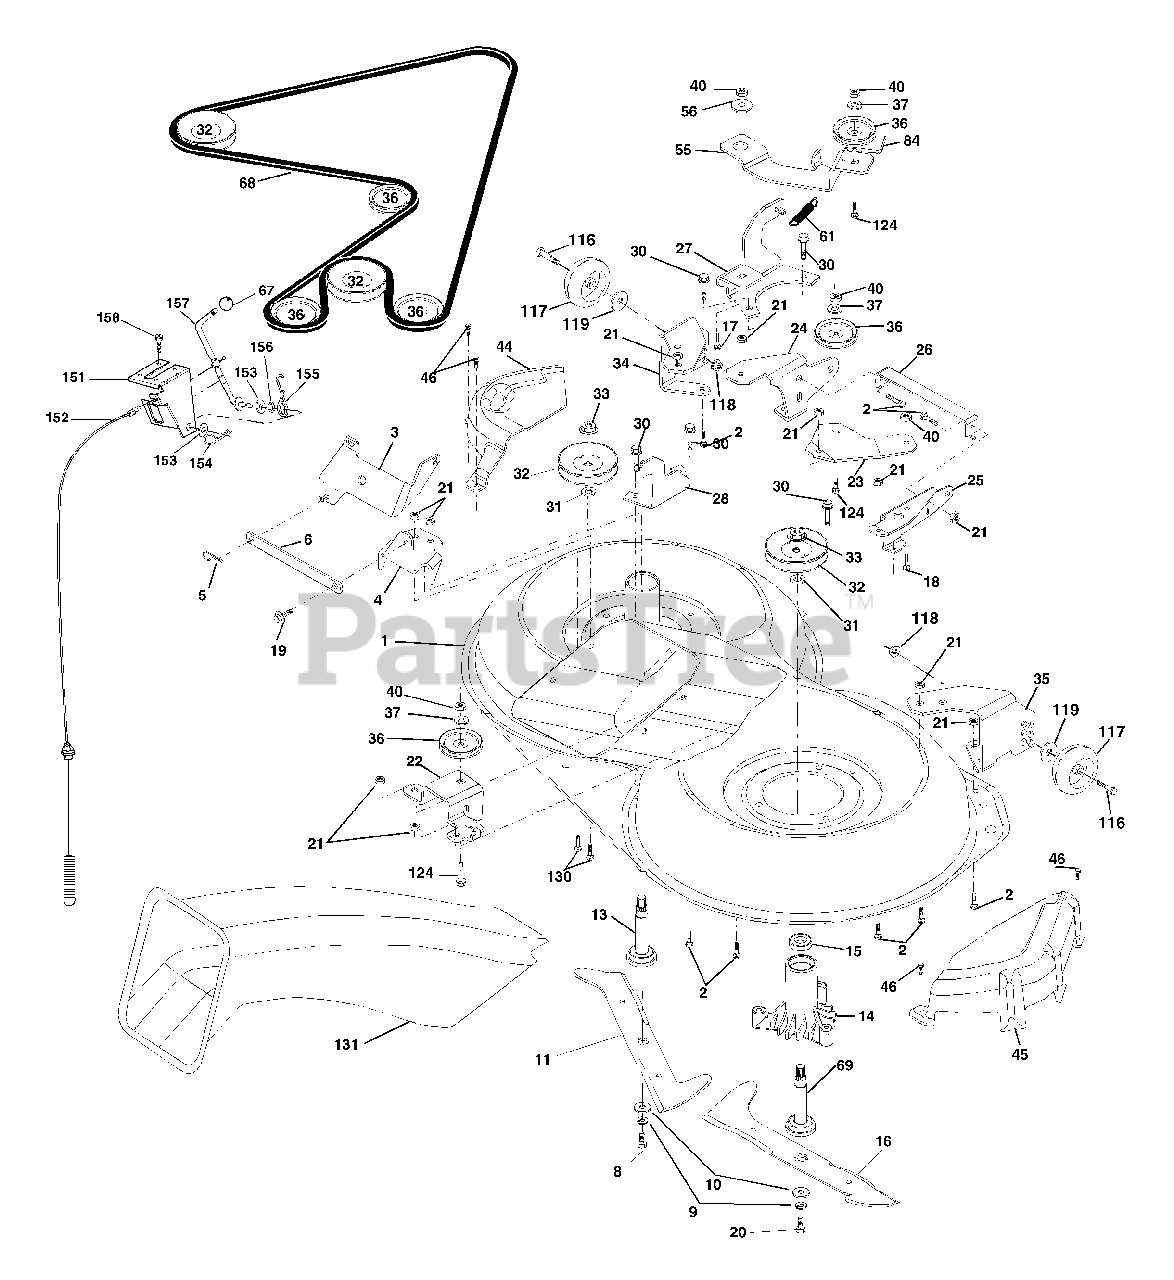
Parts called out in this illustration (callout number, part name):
1	Housing Asm. Mower 92 CRD
2	Bolt Rdhd Sqnk 5/16-18 Unc x 3/4
3	Bracket Asm. S-Bar Chass 92 CRD
4	Bracket Bar Sway Deck 92 CRD
5	Retainer Spring
6	Bar Sway 92 CRD
8	Bolt 3/8-24 x 1.25 Gr8 Patched
9	Washer Lock Hvy 3/8 Unplated
10	Washer Hard Blade Mower vented
11	Blade 3-1 Lh 92 CRD
12	Bearing Ball #6204 (Mandrel)
13	Shaft Asm. W/Lower Bearing
14	Housing Mandrel Vented (Machd)
15	Bearing Ball Mandrel
16	Blade 3-1 Rh 92 CRD
17	Bolt Carriage 3/8-16 x 1-1/4
18	Bolt Rdhd Sqnk 3/8-16 x 1 Gr5
19	Bolt Shoulder 5/16-18 Thd Form
20	Bolt 3/8-24 x 1.25 Gr8 Ptch Lhthd
21	Nut Crown Lock 5/16-18
22	Bracket Idler Sprt RR 92 CRD
23	Bracket Idler Sprt RF 92 CRD
24	Bracket Suspension LF 92 CRD
25	Bracket Suspension RF 92 CRD
26	Brace Support Susp Frt CRD
27	Bracket Asm. Susp RR 92 CRD
28	Bracket Asm. Susp LR 92 CRD
30	Screw Thd Rolling Washer Head
31	Washer Spacer Mower Vented
32	Mandrel Pulleys 36 & 46
33	Nut Flg Top Lock Cntr B 9/16
34	Bracket Gauge Wheel Lf 92 CRD
35	Bracket Gauge Wheel Rf 92 CRD
36	Pulley Idler V-Groove Dim 4.25
37	Washer 11/32 x 13/16 x 16 Ga
40	Nut Crownlock 3/8-16 Unc
44	Cover Mandrel Lh 92 CRD
45	Cover Mandrel Rh 92 CRD
46	Screw Thd Roll 1/4-20 x 5/8
55	Arm Idler 92 CRD
56	Spacer Retainer Mower
61	Spring Tension Belt
67	Knob Rd 3/8-16 Plstc Thds Blk
68	Hex-Belt 92 Mower 105AA
69	Shaft Asm W/Lwr Brg Rh Thd CRD
84	Keeper Belt Idler
116	Bolt Shoulder
117	Wheel Gage Donut Wide
118	Nut Centerlock 3/8-16 Unc
119	Washer 3/8 x 7/8 x 14 Ga.
124	Bolt Carr Sh 3/8-16 x 1-1/2 Gr5
128	Washer Felt
130	Bolt Rdhdsqnk 5/16-18 Unc x 3/4
131	Chute Bagger CRD 92cm
151	Bracket Clutch Cable
152	Cable Clutch CRD
153	Washer Flat 3/8" Type B
154	Spring Retainer
155	Spring Retention
156	Spacer Clutch Cable
157	Rod Clutch Cable 3/8"
158	Screw Hex Thd Cut 1/4-20 x 5/8
